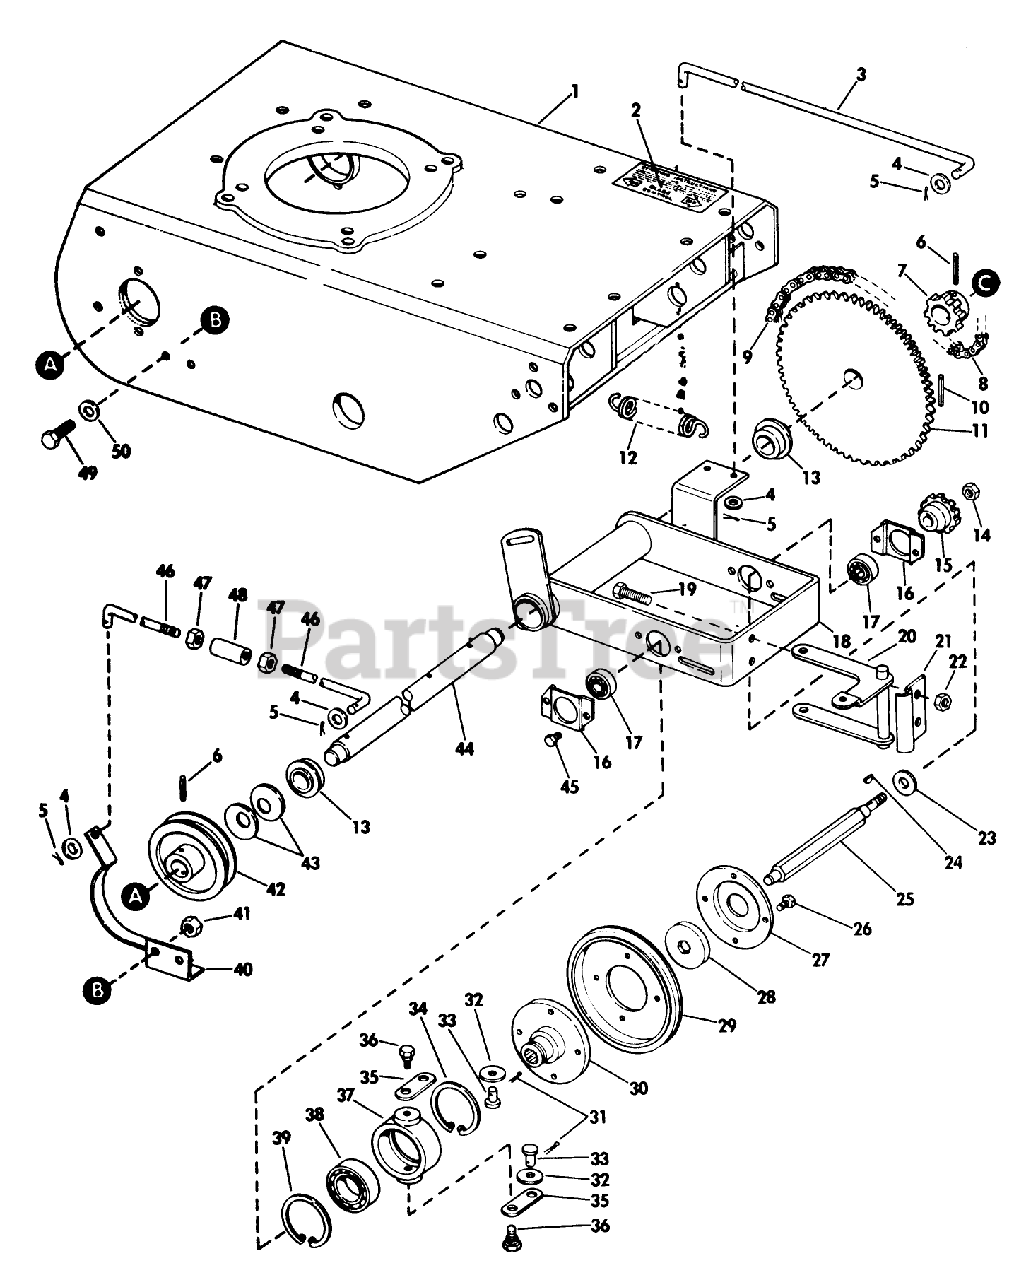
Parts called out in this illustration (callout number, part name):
14	LOCKNUT
29	DRIVE WHEEL
47	STOP NUT
